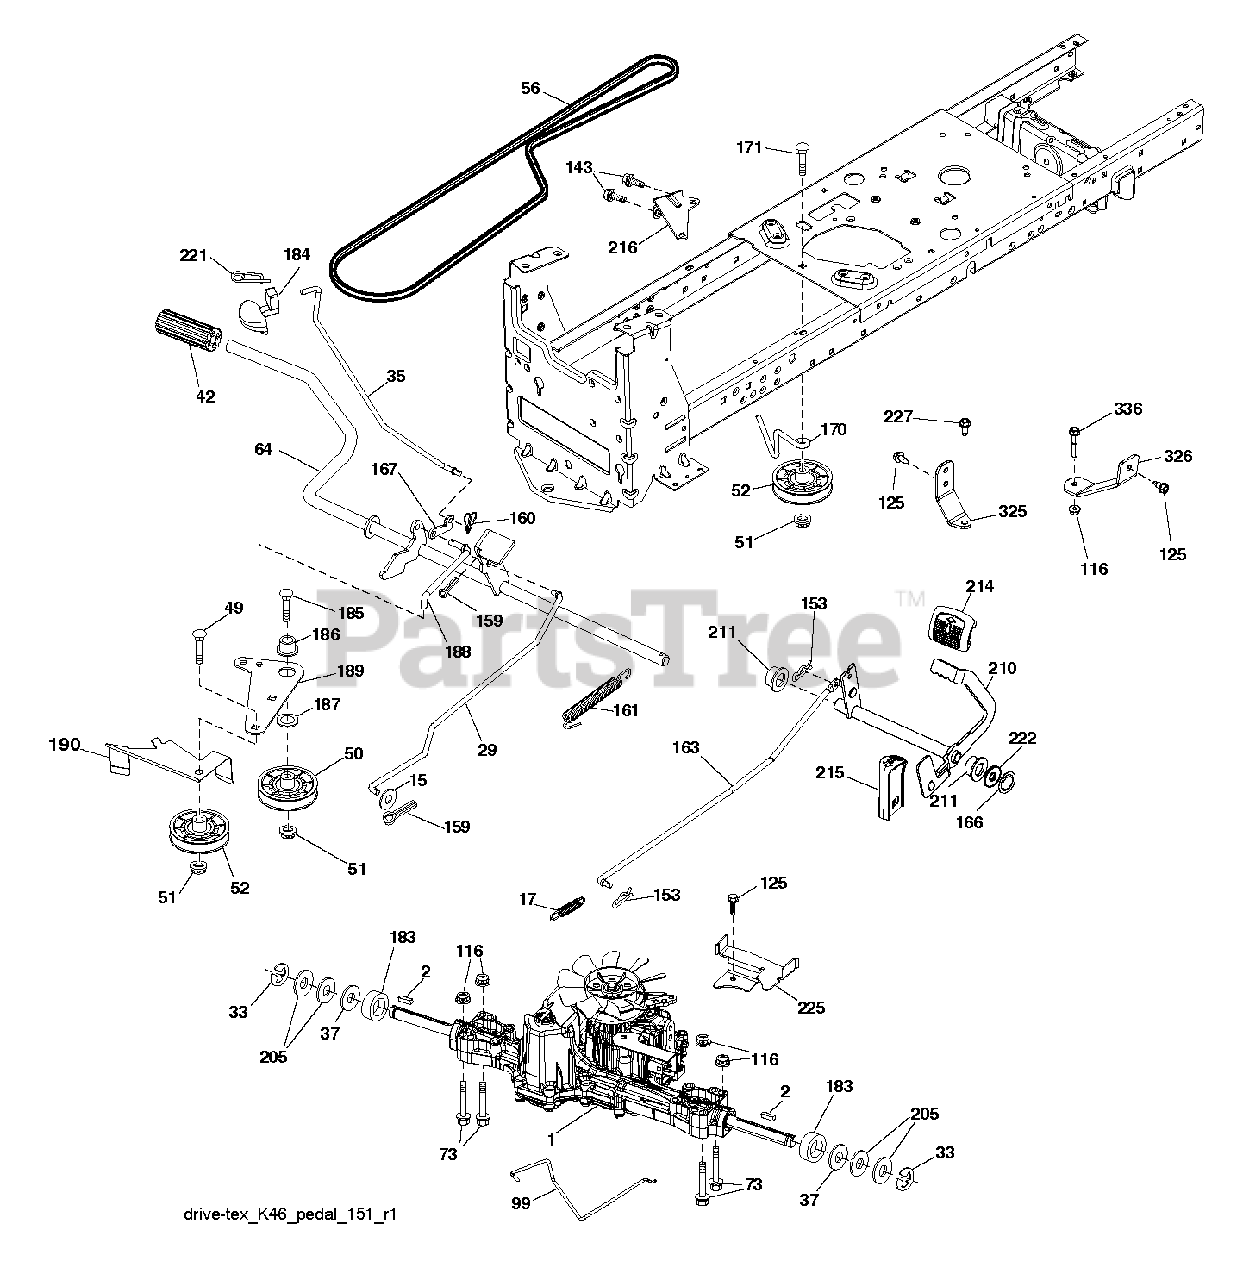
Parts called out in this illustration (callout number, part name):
2	SQUARE KEY
17	SPRING.BRAKE.K46.GREEN
29	ROD.BRAKE.K46
33	E-RING LT
35	ROD .BRAKE. PARKING. GT. HUSQ.
37	WASHER.HARDENED
49	BOLT
50	IDLER.FLAT.910.OFFSET
51	NUT LOCK FLG 3/8-16 UNC
52	IDLER.V-GROOVE.910.OFFSET
56	V-BELT.MOWER.92.40.42/K46
64	SHAFT.ASM.PEDAL.BRK.CNTR
73	BOLT HEX 5/16-18 GR 5
99	ROD.SPRING.BYPASS.K46.LT.Z
116	NUT LOCK HEX FLANGE 5/16-18
125	SCREW
143	SCREW LT
159	COTTER PIN
160	RETAINER CLIP
161	SPRING, RETURN LT
163	ROD.CONTROL.K57R.K46
166	NUT.PUSH.625
167	LATCH.BRAKE.SPRING
170	KEEPER.V-IDLER.CENTER.
171	BOLT
183	SPACER AXLE
186	SPACER.RETAINER
187	WASHER 12/32X2X10GA
188	LINK.CLUTCH.GROUND.DRIVE
189	BELLCRANK.GROUND.DRIVE.TEX.
190	KEEPER.BELLCRANK.DRIVE
210	ROCKER.ASM.PEDAL.CONTR
211	BEARING.NYLON
214	PEDAL.FORWARD.PAD.TEX
215	PEDAL.REVERSE.TEX.GT.4
216	BRACKET.PULLEY.IDLER.W/TEX
221	RETAINER.SPRING.CLIP.H
222	WASHER 21/32 X 1-1/4 X 10 GA.
225	KEEPER.BELT.TRANSAXLE.K46
227	Screw, Lt
325	Torque Strap Bracket, 46 20" Tire LH
326	Torque Strap Bracket, 46 20" Tire RH
336	Flanged Hex Bolt, 5/16-18 X 1-3/4
